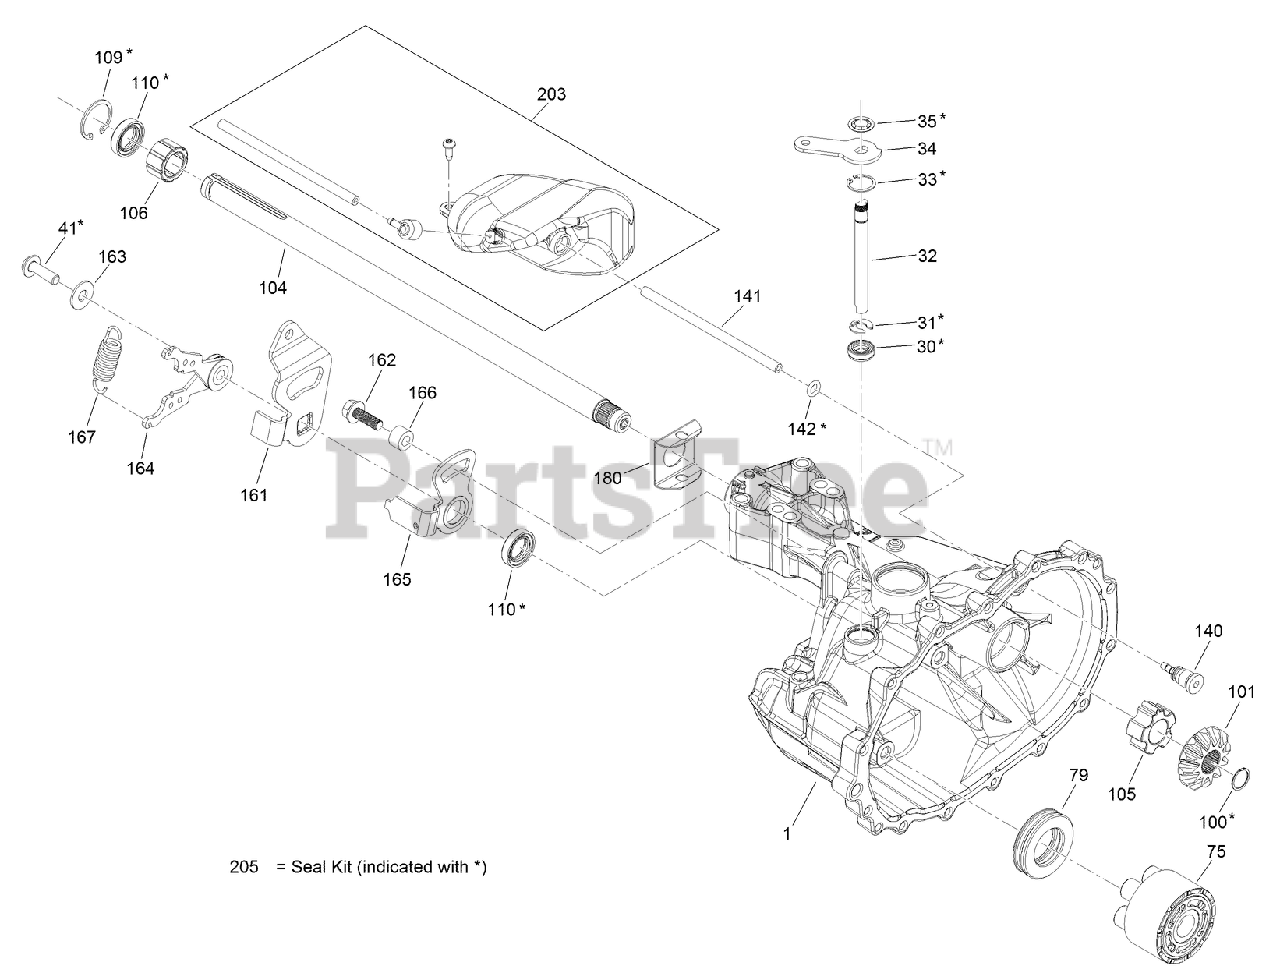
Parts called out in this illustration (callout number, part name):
1	MAIN HOUSING KIT
30	SEAL-LIP
31	RING-RETAINING, EXTERNAL
32	ROD-BYPASS, ACTUATOR
33	RING-RETAINING, INTERNAL
34	ARM-BYPASS
35	RING-RETAINING, EXTERNAL
75	CYLINDER BLOCK KIT
79	BEARING-THRUST
100	RING-RETAINING, SPIRAL
101	GEAR-BEVEL, 12T (SPLINE, ID)
104	SHAFT-AXLE, KEYED
105	BUSHING-INBOARD
106	BUSHING-OUTBOARD
109	RING-RETAINING, INTERNAL
110	SEAL-LIP
140	FITTING-SAE
142	O-RING
161	ARM-CONTROL, RETURN
162	SCREW-HF
163	WASHER
164	BI DIRECTIONAL RETURN KIT
165	ARM-NEUTRAL
166	BUSHING
167	SPRING-EXTENSION
180	SPRING CLIP-HOUSING THRUST
203	EXPANSION TANK KIT
205	SEAL KIT
